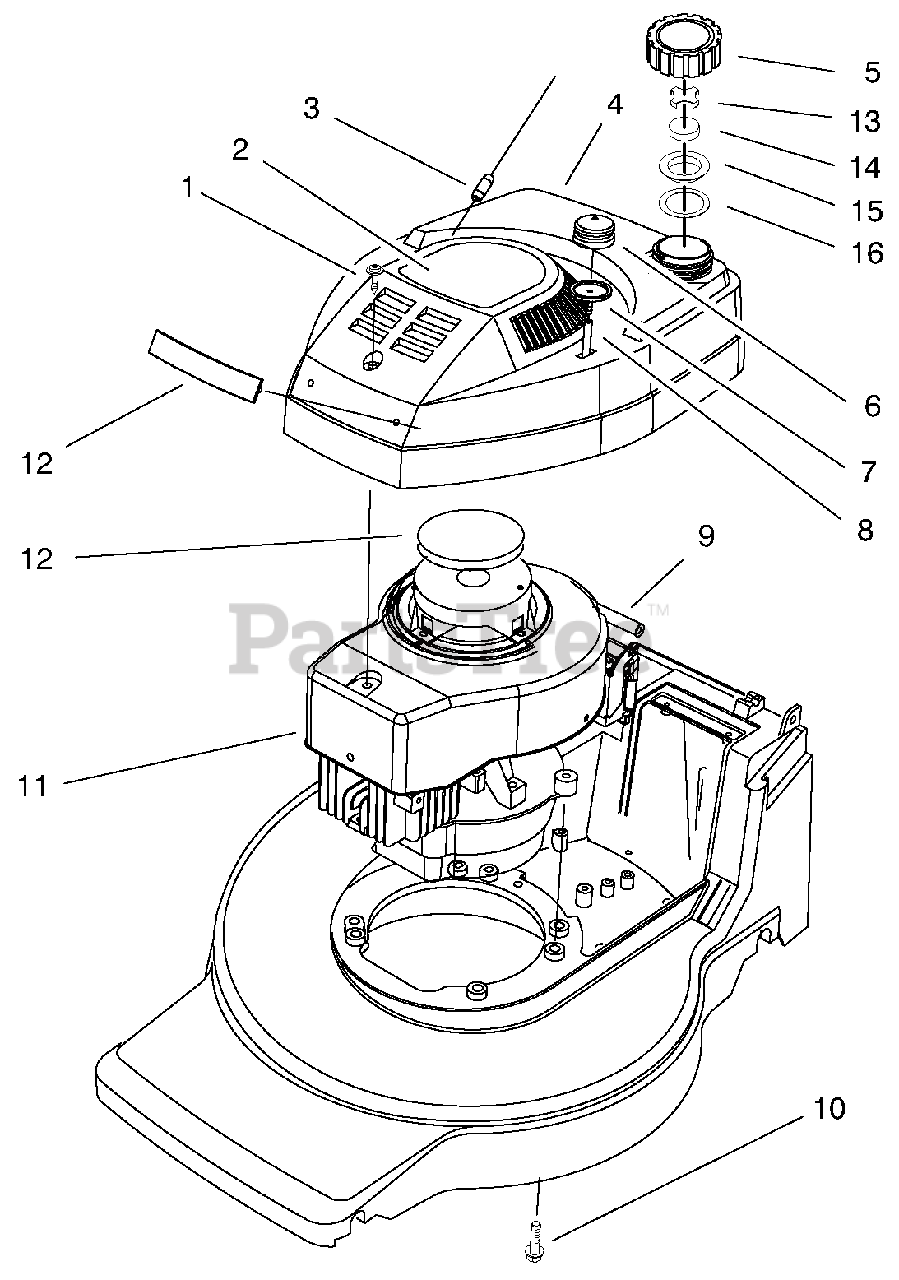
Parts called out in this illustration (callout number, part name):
1	Screw-Sems
2	Decal-Shroud
3	Rope-Stop
4	Tank Shroud Assembly
5	Cap-Gas (Incl. Ref. #13-16)
6	Bulb-Primer
7	Body-Primer
8	Hose-Primer
9	Line-Gas
10	Screw-Engine
12	Decal-Shroud
14	Baffle-Foam
17	Disc-Foam
